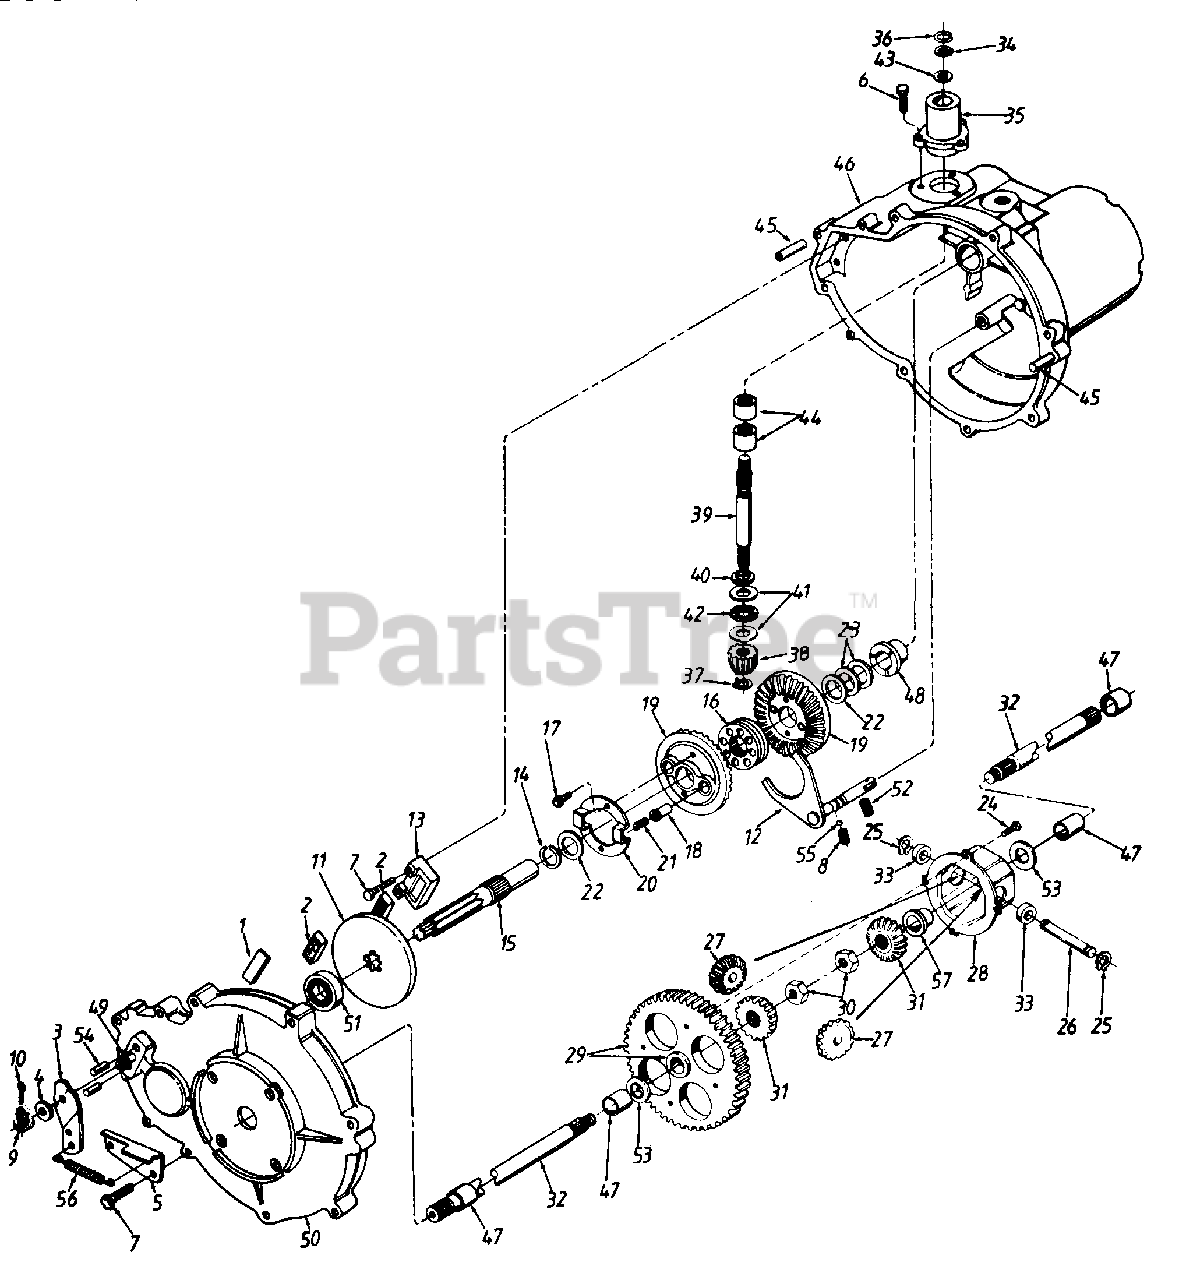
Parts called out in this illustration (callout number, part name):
1	Puck Plate
2	Brake Puck
3	Actuating Arm
4	Fl-Wash. 11/32" I.D. x 7/8" O.D.
5	Brake Stop Brkt.
6	Hex Bolt 1/4-20 x .62" Lg.
7	Hex Tap Scr. 1/4-20 x 1.25" Lg.
8	Spring Detent
9	Castle Nut 5/16-24 Thd.
10	Cotter Pin 3/32" Dia. x 1" Lg.
12	Shifter Ass'y.
13	Brake Puck Holder
14	Retaining Ring
16	Shift Collar
17	Hex Wash. Hd. Tap Scr. 1/4-20 x.38" Lg.
18	Drive Pin
19	Bevel Gear Ass'y.
20	Spring Retaining Plate
21	Drive Spring
22	Fl-Wash. .915" I.D. x 1.5" O.D.
23	Fl-Wash. .915" I.D. x 1.37n O.D.
24	Pan Hd. Scr. 1/4-20 x .5" Lg.
25	Snap Ring
27	Miter Gear 15T
28	Differential Can Assembly
29	Differential Gear Ass'y. w/Bearing
30	Hex Ins. L-Nut 1/2-20 Thd.
31	Miter Gear
32	Axle
33	Differential Thrust Spacer
34	Retainer Ring
35	Input Bearing Housing
37	Retaining Ring
38	Pinion Input 14T
40	Seal 5/8" l.D.
41	Thrust Wash. .621" I.D. x 1.12"
42	Thrust Bearing
43	Fl-Wash. 5/8n l.D. x 1.0" O.D.
44	Needle Brg. 518" x 112" Lg.
46	R.H. Housing
47	Sleeve Bearing 314" I.D.
48	Flange Bearing .906" l.D.
49	Sq. Head Bolt 5/16-24 Thd.
50	L.H. Housing
51	Ball Bearing .669" l.D.
52	Set Screw 5/16-18 x 318" Lg.
53	Fl-Wash. .76" I.D. x 1.5n O.D.
54	Brake Actuating Pin
56	Ext. Spring 1.14n Lg.
57	Differential Flange Brg.
